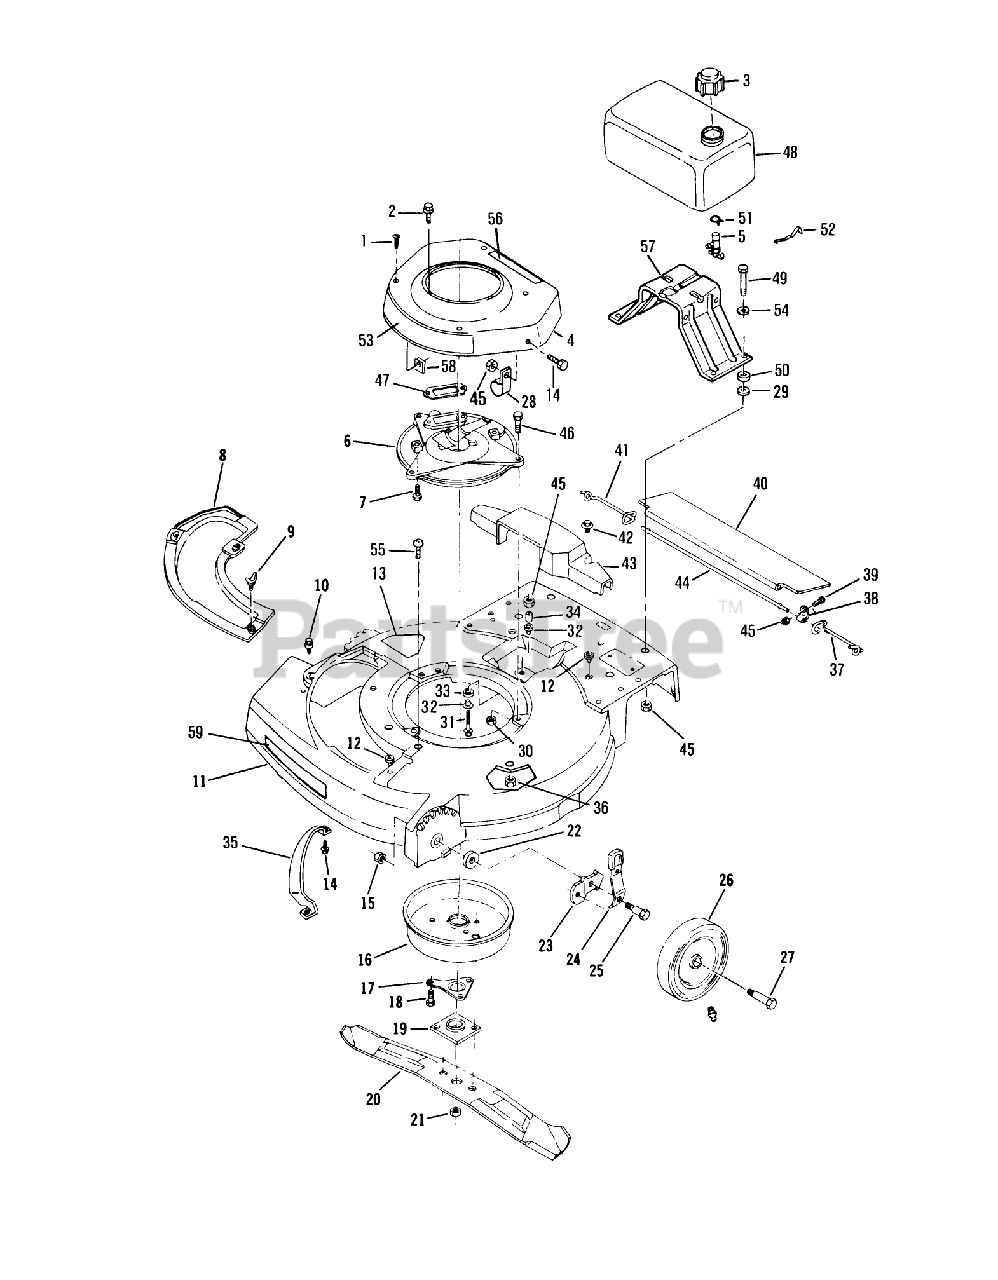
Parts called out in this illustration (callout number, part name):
1	SCREW - SELF TAPPING
2	SCREW SEMS SM
3	FUEL CAP & INSERT
5	VALVE&SCREEN SM
6	PLATE F
7	SCREW V
9	WING SCREW LAWRE
15	LOCKNUT
16	MUFFLER COVER F
17	SUPPORT F
18	SCREW
19	PLATE AND COLLAR ASM
21	NUT-BLADE
22	WASHER
24	SPRING ARM ASM
25	BOLT
26	WHEEL & TIRE
27	BOLT-SHOULDER
29	WASHER
30	NUT-LOCK F
32	SPACER ECK PRES
33	GROMMET
34	SPACER
35	BAR-TOE
36	LOCKNUT E
37	SPRIG T/SHLD ASOC
38	CLAMP ROD KMC
40	SHIELD
41	SPRING;TRAILING SHIELD RH
42	SCREW SEMS TRM HEX HD
43	COVER
44	ROD 21" ADVANCE
45	LOCKNUT E
46	SCREW-HH
48	TANK - FUEL
49	BOLT PIONEER
51	CLAMP - HOSE S
52	SPRING
54	WASHER
57	BRACKET
58	PUSHNUT F
